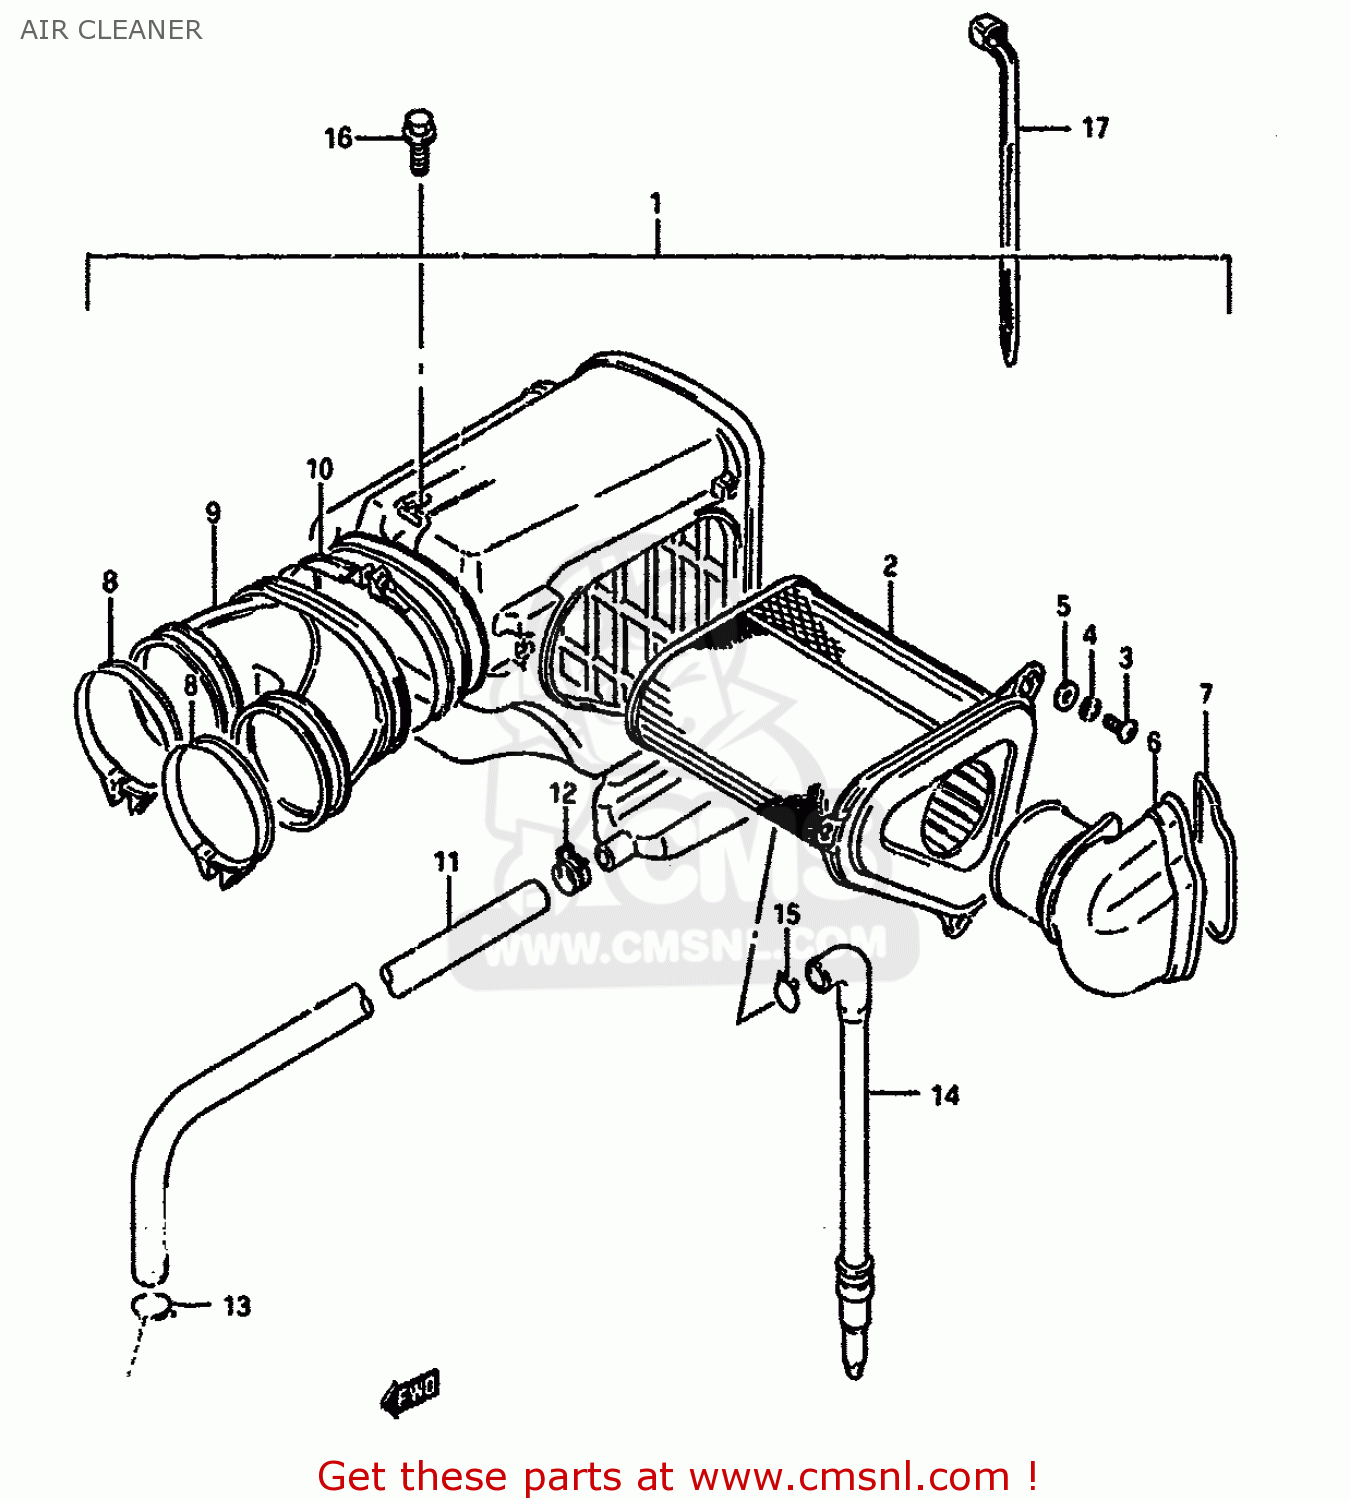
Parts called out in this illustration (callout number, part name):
1	CLEANER ASSY,A
2	FILTER ASSY
3	SCREW
4	LOCK WASHER
5	WASHER
6	TUBE,INLET
7	RING
8	CLAMP
9	TUBE,AIR CLEANER OUTLET
10	CLAMP
11	TUBE,BREATHER
12	CLIP
13	CLIP
14	TUBE,DRAIN
15	CLIP
16	BOLT 6X16
17	CLAMP(L:165)
